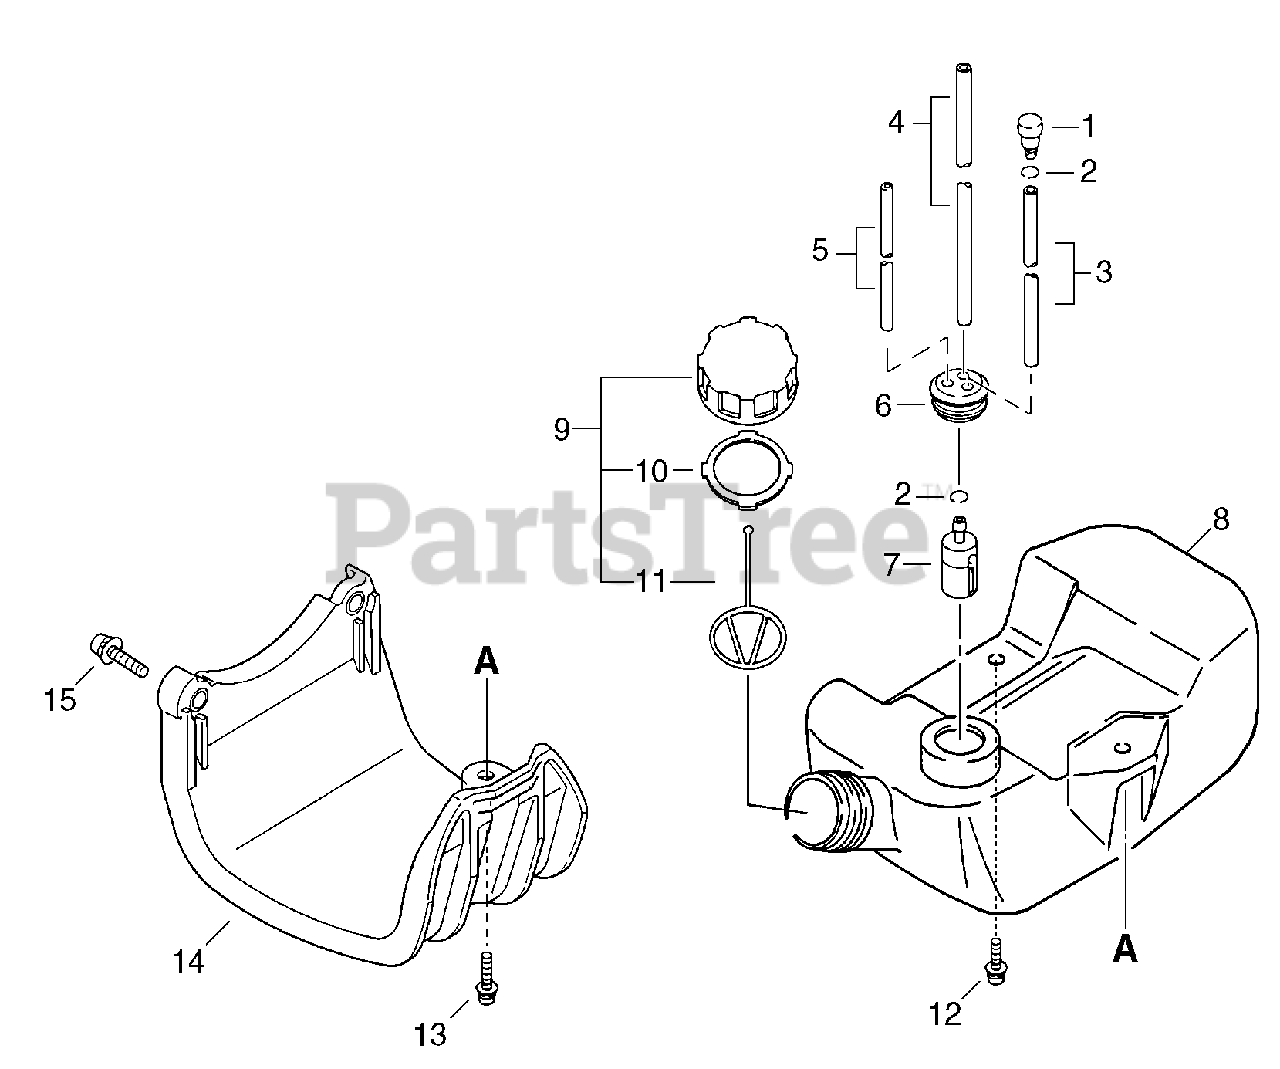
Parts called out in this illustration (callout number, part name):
1	VENT, FUEL TANK
2	CLIP - 6.5
3	PIPE - 3X6X100 -- BLACK
4	PIPE - 3X6X170 -- BLACK
5	PIPE - 3X6X60 -- CLEAR
6	GROMMET
7	FILTER, FUEL
8	TANK, FUEL
9	CAP ASSY - ORANGE
10	GASKET, CAP
11	CONNECTOR, CAP
12	SCREW - 5X16
13	SCREW - 5X20
14	GUARD, FUEL TANK
15	SCREW - 5X22
